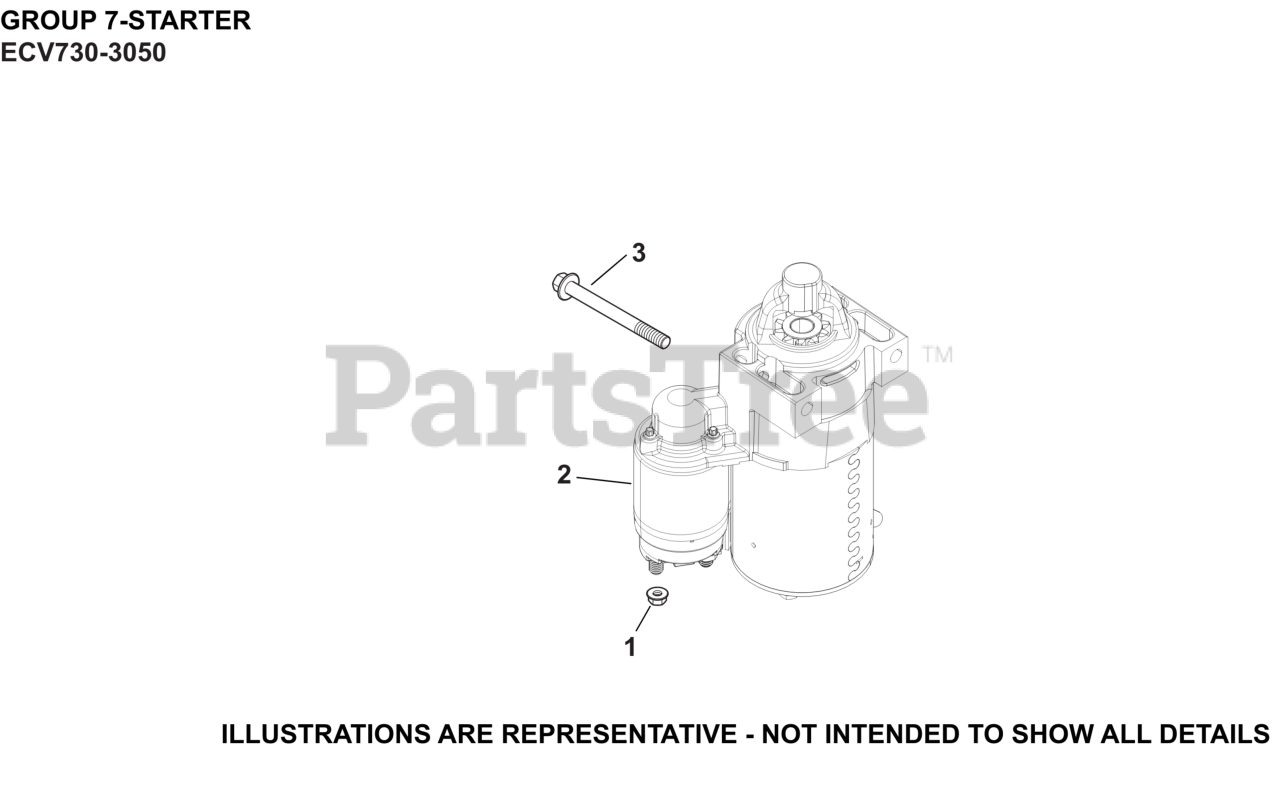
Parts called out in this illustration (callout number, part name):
1	NUT, FLG M8X1.25
2	STARTER, SOLENOID SHIFT (25 098 09-S)
3	SCREW, FLG M8X1.25X80
